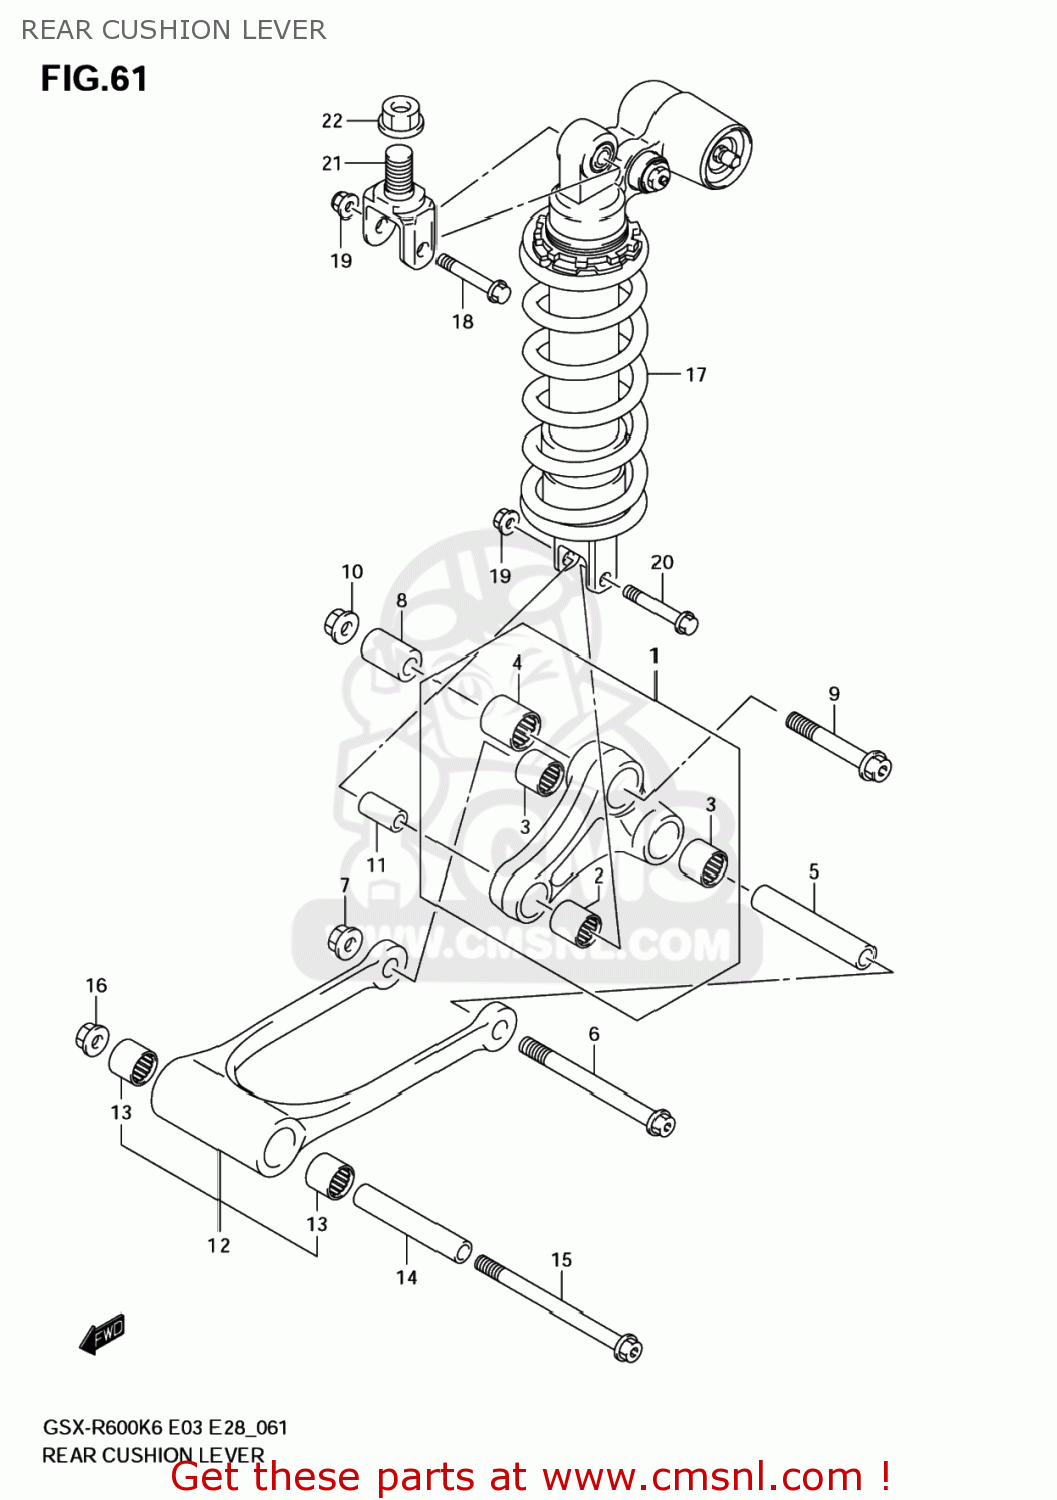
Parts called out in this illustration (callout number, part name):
1	LEVER SET,RR CUSHION
2	BEARING(17X24X26)
3	BEARING(17X24X25)
4	BEARING(20X27X32)
5	SPACER,RR CUSHION ROD
6	BOLT,RR CUSHION LEVER LWR
7	NUT,RR CUSHION
8	SPACER,RR CUSHION LEVER FR
9	BOLT, UPPER
10	NUT,RR CUSHION
11	SPACER,RR CUSHION LEVER
12	ROD SET,RR CUSHION
13	BEARING(17X24X25)
14	SPACER,RR CUSHION LEVER CTR
15	BOLT,RR CUSHION ROD
16	NUT,RR CUSHION
17	ABSORBER ASSY,RR SHOCK(YELLOW)
18	BOLT (10X55)
19	NUT,REAR AXLE
20	BOLT (10X55)
21	BRACKET,RR SHOCK ABSORBER UPR
22	NUT
